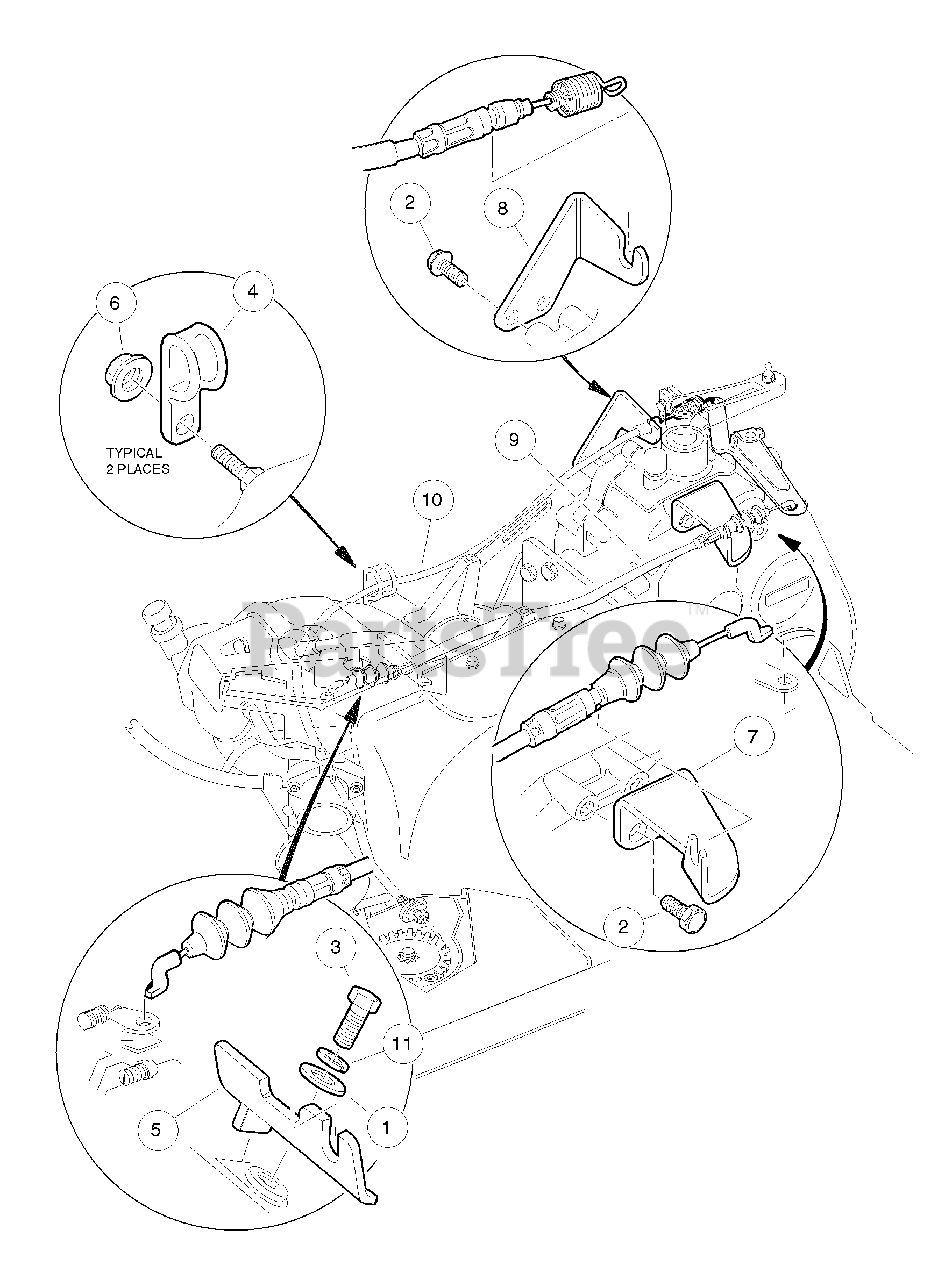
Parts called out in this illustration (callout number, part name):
1	Washer, 5/16 Flat
2	Screw, 1/4 X 0.625 Hex-Head
3	Screw, M8-125 X 22 Hex-Head
5	Bracket, Governor Cable Snap-In
7	Bracket, Rear Governor Cable Snap-In
8	Bracket, Rear Accelerator Cable Snap-In
9	Cable, Governor, Snap-In
10	Cable, Accelerator, Snap-In
11	Lockwasher, 5/16 Split
